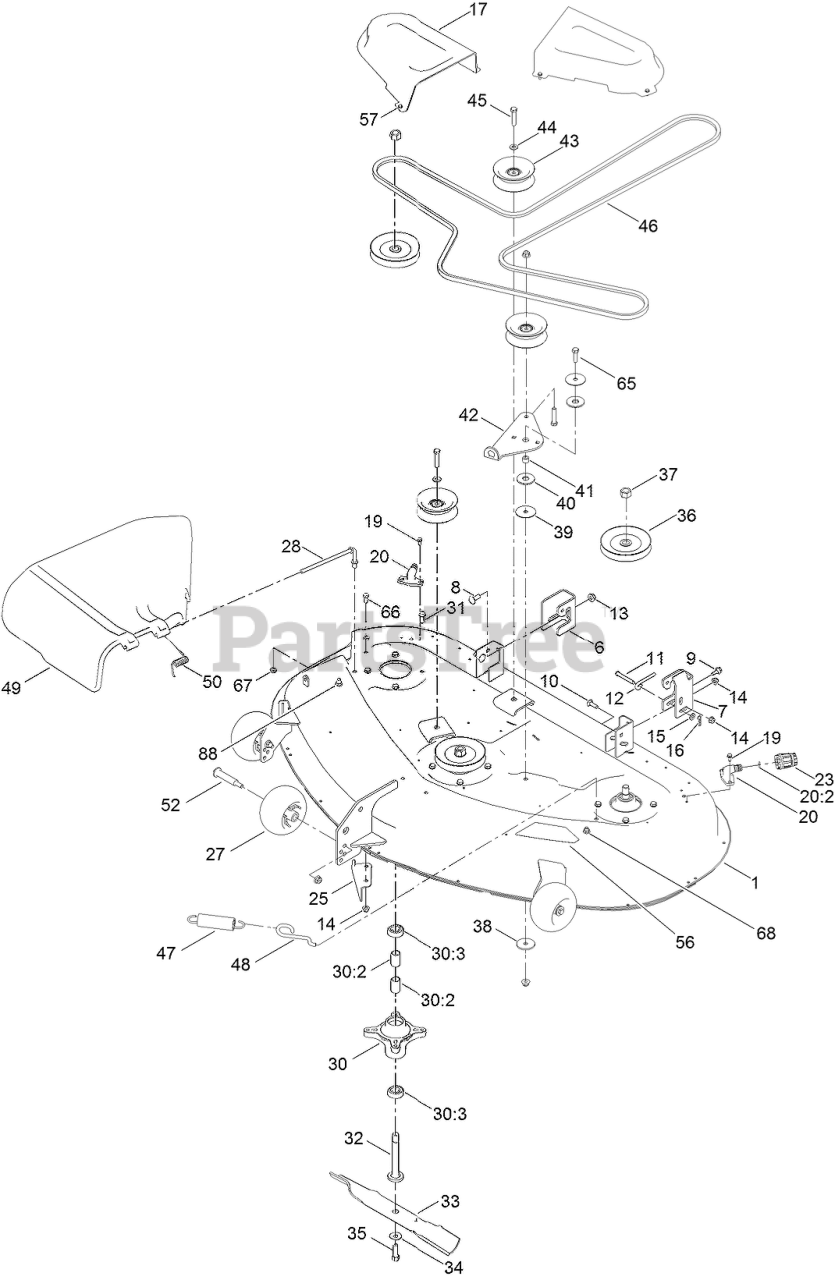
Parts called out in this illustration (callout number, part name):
1	50 INCH DECK AND DECAL ASM
6	BRACKET-HANGER, RH
7	BRACKET-HANGER, LH
8	BOLT-CARR
9	SCREW-SHOULDER, HHF
10	SCREW-CARR
11	PIN-CLEVIS
12	ROD-LEVEL, DECK
13	NUT-HF, NI
14	NUT-HF, NI
15	WASHER-PLAIN
16	PIN-COTTER
17	COVER-BELT
19	SCREW-HWH
20	FITTING-WASHOUT
20:2	O-RING
23	CONNECTOR-HOSE
25	BAFFLE-CUTOFF
27	ROLLER-SCALP, ANTI
28	ROD-PIVOT
30	SPINDLE ASM
30:2	SPACER
30:3	BEARING-BALL
31	SCREW-TAPTITE
32	SHAFT-SPINDLE
33	BLADE-HI LIFT
34	WASHER-BELLEVILLE
35	SCREW-HH
36	PULLEY
37	NUT-HEX
38	WASHER-REBOUND
39	WASHER
40	WASHER-FRICTION, COMPOSITE
41	SPACER
42	ARM-IDLER
43	PULLEY-IDLER, FLAT
44	WASHER-FLAT
45	SCREW-HH
46	V-BELT
47	SPRING-EXTENSION
48	HOOK-RETURN, SPRING
49	DEFLECTOR
50	SPRING-TORSION
52	BOLT-SHOULDER
57	SCREW-TAPTITE
65	SCREW-HH
66	SCREW-HH
67	NUT-LOCK, NI
68	SCREW-HH
88	SCREW-CARR
